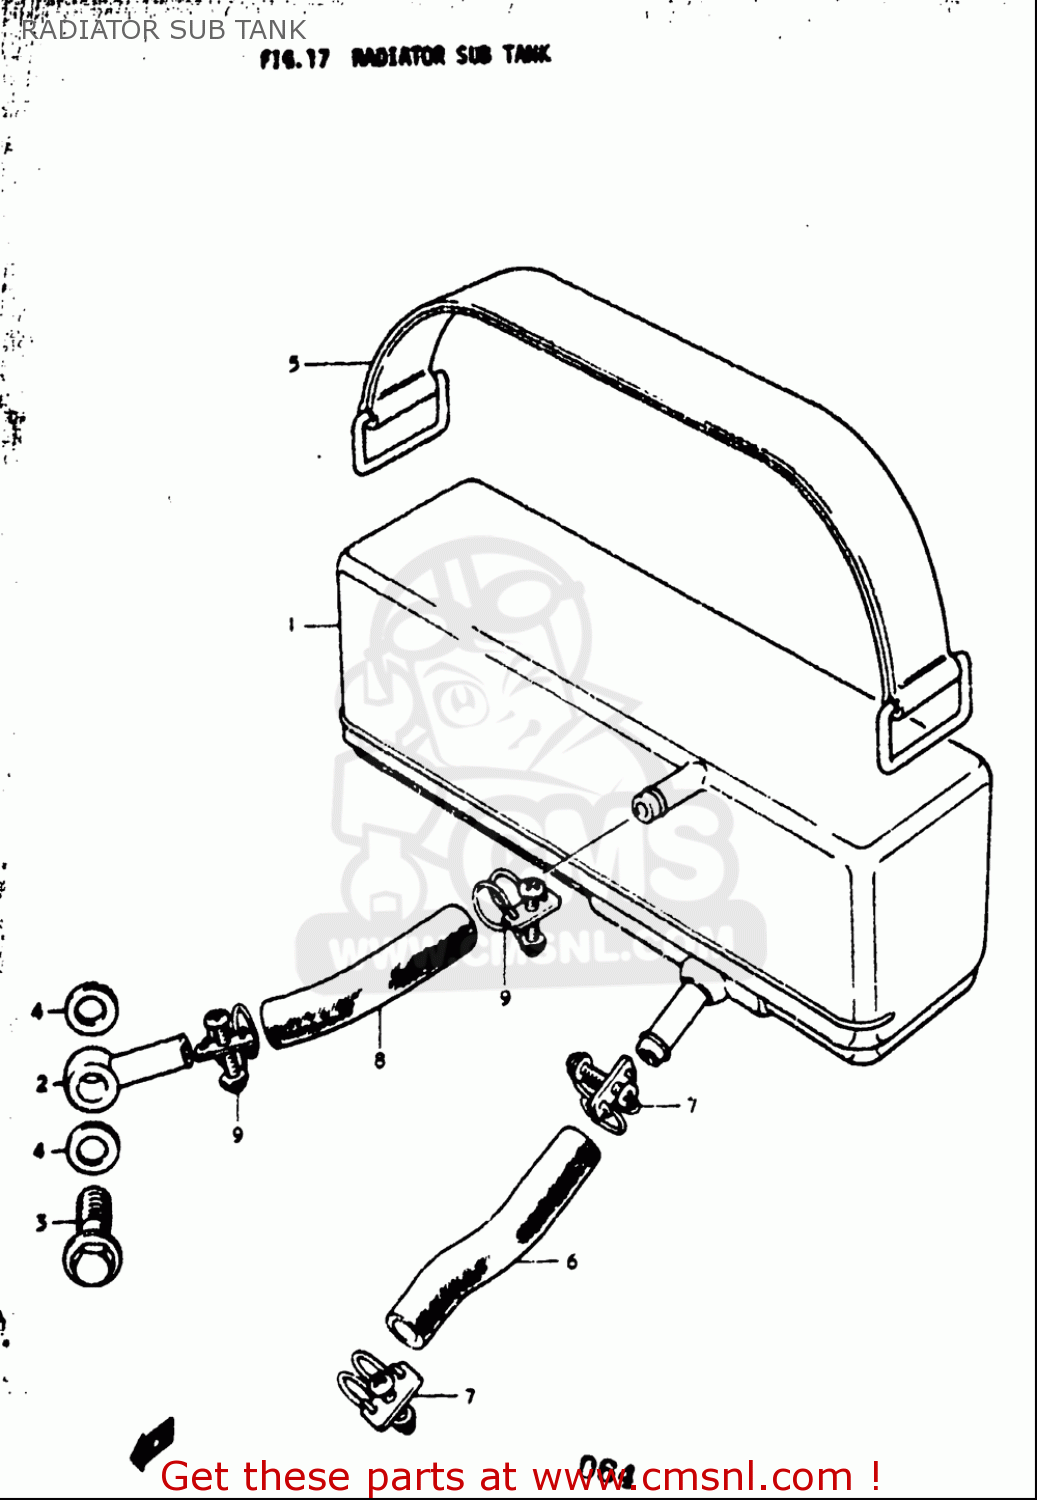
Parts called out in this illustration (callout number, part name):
2	UNION
3	UNION BOLT
4	GASKET(6.2X11X1).2 (NAS)
5	BAND
6	HOSE(5.5X9.5X400)
7	CLAMP
8	HOSE(5.5X9.5X52)
9	CLAMP
